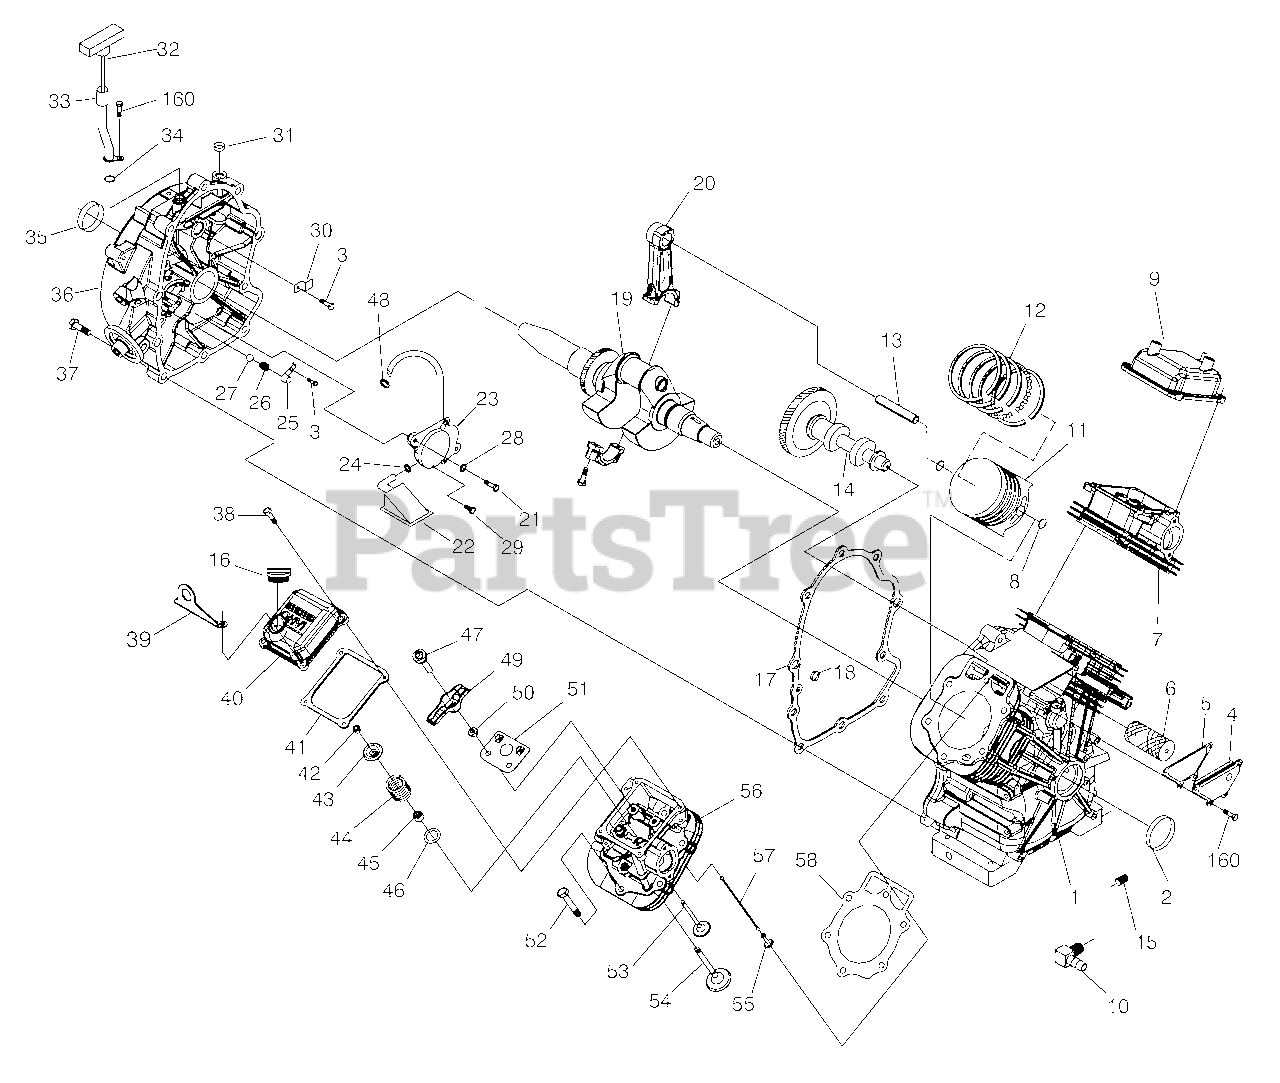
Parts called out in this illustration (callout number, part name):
1	ASSEMBLY, CRANKCASE HOUSING WITH SLEEVE
2	SEAL, 38 I.D. CRANKSHAFT
3	SCREW, TAPTITE M6-1.0 X 12 BP
4	ASSEMBLY, BREATHER
5	GASKET, BREATHER COVER
6	SEPARATOR, OIL BREATHER
7	ASSEMBLY, HEAD #1
8	RETAINER, PISTON PIN 20
9	ASSY,ROCKER COVER W/BARB
10	BARBED EL 90 3/8NPT X 3/8
11	PISTON, LC (GT-990)
12	SET, PISTON RING 90MM
13	PIN PISTON
14	ASSEMBLY, CAMSHAFT & GEAR
15	PLUG STD PIPE 3/8 STEEL SQ HD
16	ASSEMBLY, OIL FILL CAP
17	GASKET, CRANK CASE
18	SEAL, OIL PASSAGE
19	ASSEMBLY, CRANKSHAFT HORIZONTAL DIRECT DRIVE (GT-990)
20	ASSEMBLY, CONNECTING ROD (GT-990)
21	SCREW SHC M6-1.0 X 50 G8.8
22	SCREEN, OIL PICKUP
23	ASSEMBLY, OIL PUMP
24	O-RING, 0.49 ID X 0.07 THICK
25	COVER, OIL RELIEF
26	SPRING, OIL RELIEF
27	BALL, 1/2D OIL RELIEF
28	WASHER, LOCK RIB M6
29	SCREW, PLASTITE HI-LOW #10
30	CLAMP, OIL TUBE
31	PLUG-CRANKCASE GOVERNOR BORE
32	ASSEMBLY, DIPSTICK WITH HANDLE
33	TUBE, DIPSTICK
34	O-RING, OIL CLR
35	SEAL, 42 I.D. CRANKSHAFT
36	ASSY, GEAR COVER / ADAPTOR W/SLEEVE
37	SCREW, HHFC M10-1.5 X 55
38	SCREW HHFC M6-1.0 X 25
39	LIFT HOOK, GT990/760
40	COVER,ROCKER W/OIL FILL "GENERAC" TEXT
41	GASKET, VALVE COVER
42	KEEPER, VALVE SPRING
43	RETAINER, VALVE SPRING
44	SPRING, VALVE
45	SEAL, VALVE STEM D7
46	WASHER, VALVE SPRING
47	STUD, ROCKER ARM PIVOT
48	O-RING, 3/8" X 1/2"
49	ROCKER ARM
50	NUT, HEX M8-1.0 GB YELLOW CHROM
51	PLATE, PUSH ROD GUIDE
52	SCREW HHFC M8-1.25 X 65
53	VALVE, EXHAUST
54	VALVE, INTAKE
55	TAPPET, SOLID
56	ASSEMBLY, HEAD #2
57	PUSHROD 147
58	GASKET, HEAD
59	KIT GEAR COVER
60	KIT GASKET
61	KIT PISTON & RINGS
62	KIT BREATHER ASSEMBLY
63	KIT HEAD ASSEMBLY CYLINDER 1
64	KIT HEAD ASSEMBLY CYLINDER 2
65	KIT OIL RELIEF
